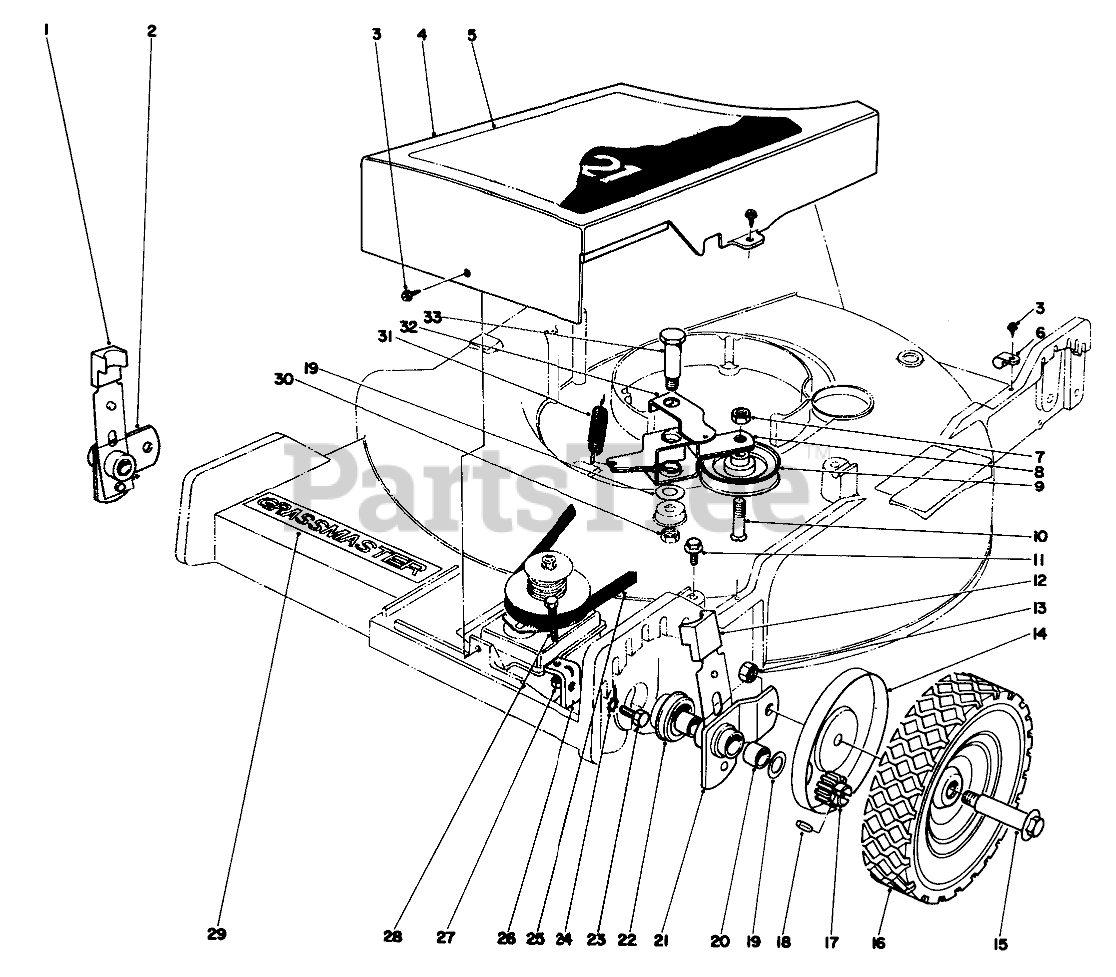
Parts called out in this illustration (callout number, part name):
1	Arm Knob
2	Pivot Arm (Incl. Ref. #20)
3	SCREW-HWHTF
4	Belt Cover
5	Decal Belt Cover
6	CLAMP-NYLON
7	NUT-HEX
8	Idler Bracket
9	V-GROOVE IDLER PULLEY
10	Screw Low Head
11	SCREW-HWHTF
12	Arm Knob
13	Nut
14	WHEEL COVER
16	Wheel & Tire
17	Pinion
18	PIN-GROOVED
19	WASHER-THRUST
20	BUSHING
21	Pivot Arm (Incl. Ref. #20)
22	End Cap
23	SCREW-HH
24	WASHER-LOCK
25	V-BELT
26	Bracket
27	NUT-JAM
28	Screw
29	Decal Grassmaster
30	NUT-HEX
31	TENSION SPRING
32	Idler Bracket Lever
33	SCREW-SHOULDER, HH
